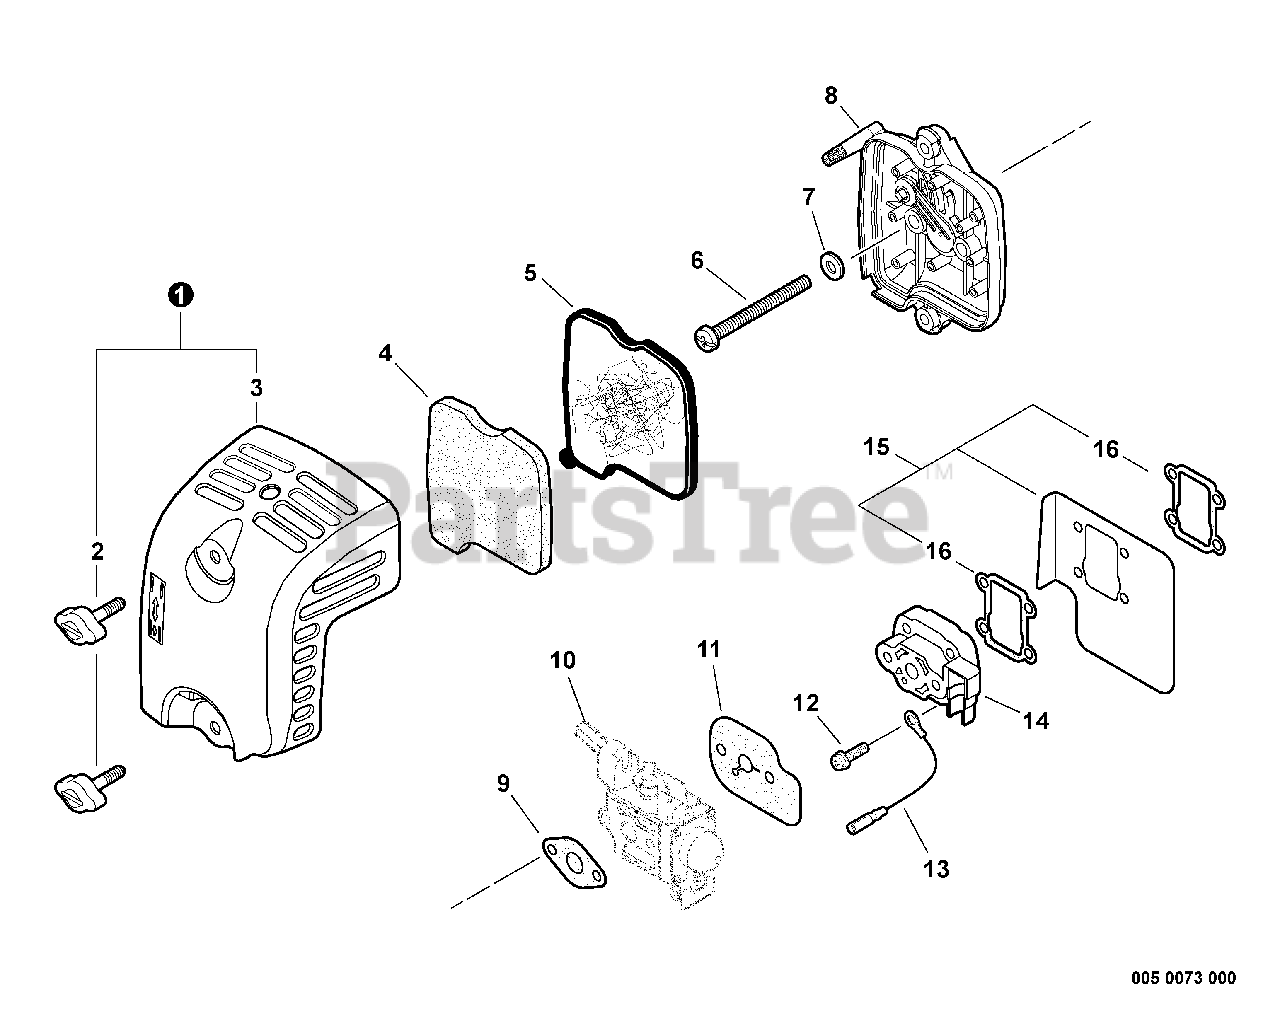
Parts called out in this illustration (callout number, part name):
1	AIR FILTER COVER ASSY
2	THUMBSCREW
3	COVER, AIR FILTER
4	PRE-FILTER -- FOAM
5	FILTER, AIR
6	SCREW - 5X60
7	WASHER - 5
8	AIR FILTER CASE ASSY
9	GASKET, INTAKE
10	CARBURETOR
11	GASKET, INTAKE
12	SCREW - 5X22
13	LEAD - GROUND
14	INSULATOR ASSY
15	INTAKE SHIELD KIT
16	GASKET, INTAKE
